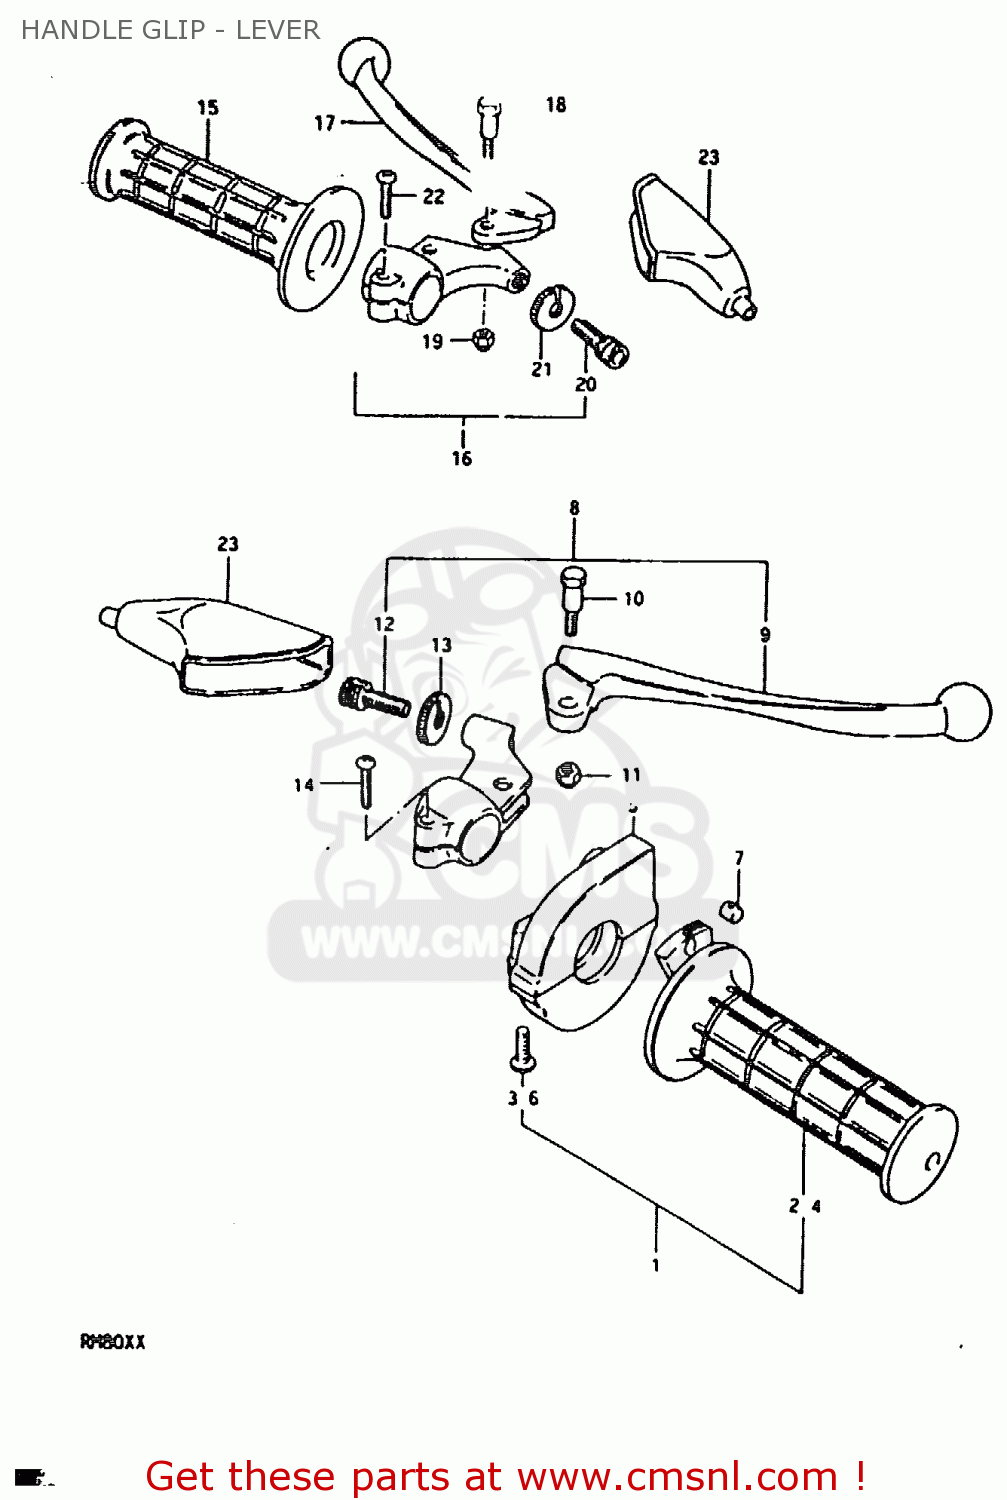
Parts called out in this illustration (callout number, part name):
1	CASE ASSEMBLY,THROTTLE
2	GRIP,THROTTLE
3	SCREW
4	GRIP,THROTTLE
5	CASE,THROTTLE
6	SCREW
7	PIECE,THROTTLE END
8	LEVER ASSEMBLY,BRAKE
9	LEVER,BRAKE
10	BOLT,LEVER
11	NUT 6MM
12	ADJUSTER,CABLE
13	NUT,CABLE ADJUSTER
14	SCREW
15	GRIP,LEFT
16	LEVER ASSY,CLUTCH
17	LEVER,CLUTCH
18	BOLT,LEVER
19	NUT 6MM
20	ADJUSTER,CABLE
21	NUT,CABLE ADJUSTER
22	SCREW
23	COVER,CLUTCH LEVER
